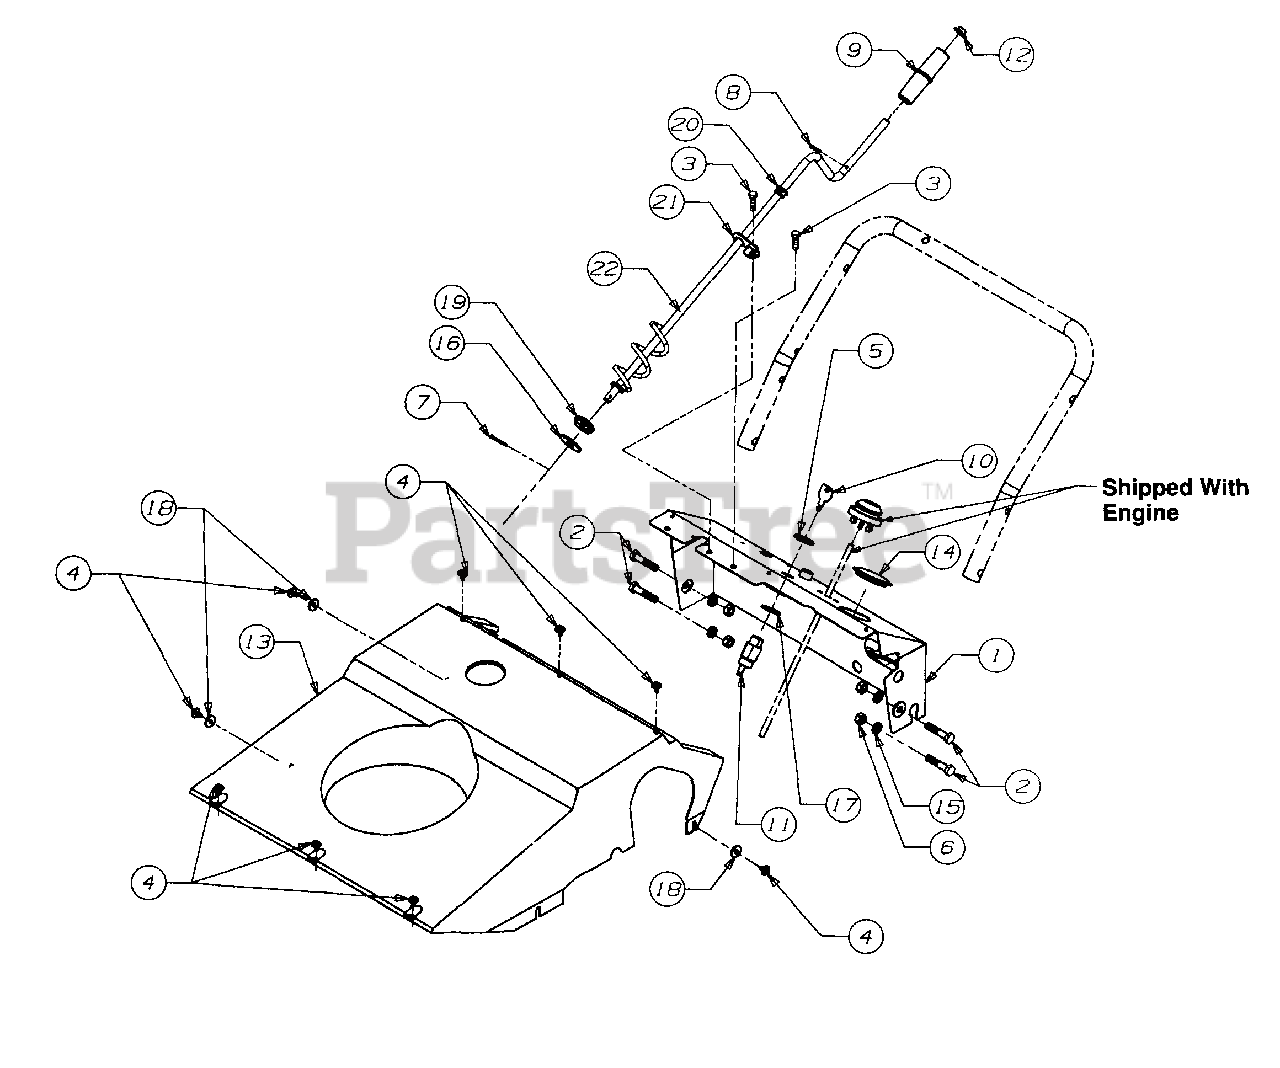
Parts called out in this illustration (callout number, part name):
3	Screw - Hex Tap
4	Screw - Hex Tap
5	Nut Hex
6	Nut - Hex
7	Pin - Cotter
8	Pin Roll
9	Knob - Chute Crank
10	Key - Ignition
11	Switch - Key
12	Nut Push
13	Shroud
15	Washer Lock
16	Washer Flat
17	Washer Internal Lock
18	Washer Flat
19	Bushing Hex
20	Bushing
21	Bracket Chute Crank
22	Crank Ass'y. Chute
